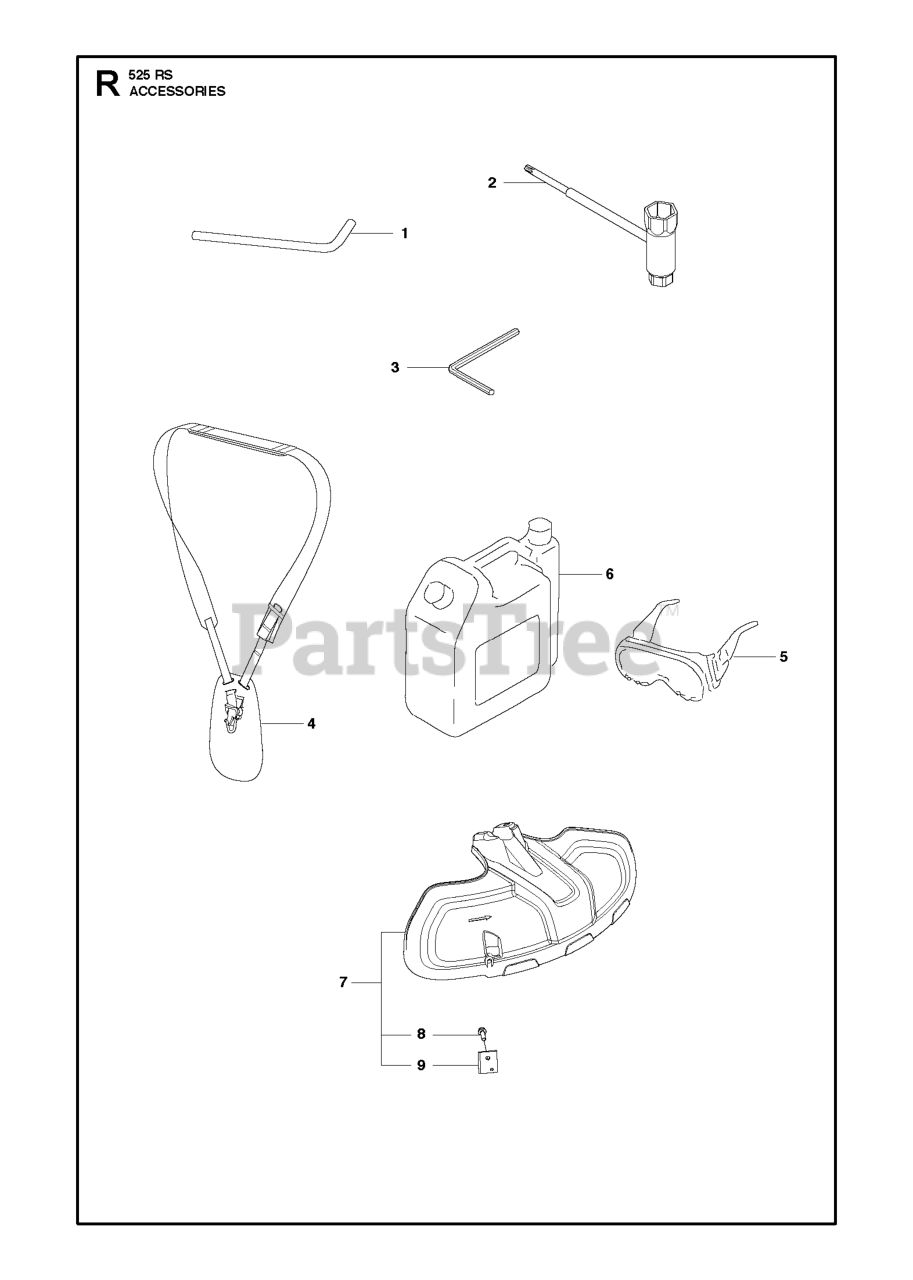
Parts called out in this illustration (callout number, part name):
2	COMBINATION WRENCH TORX
7	COMBINATION GUARD
8	SCREW ITXSCFT PW4.8X16 T27 CH
9	LINE CUTTER
